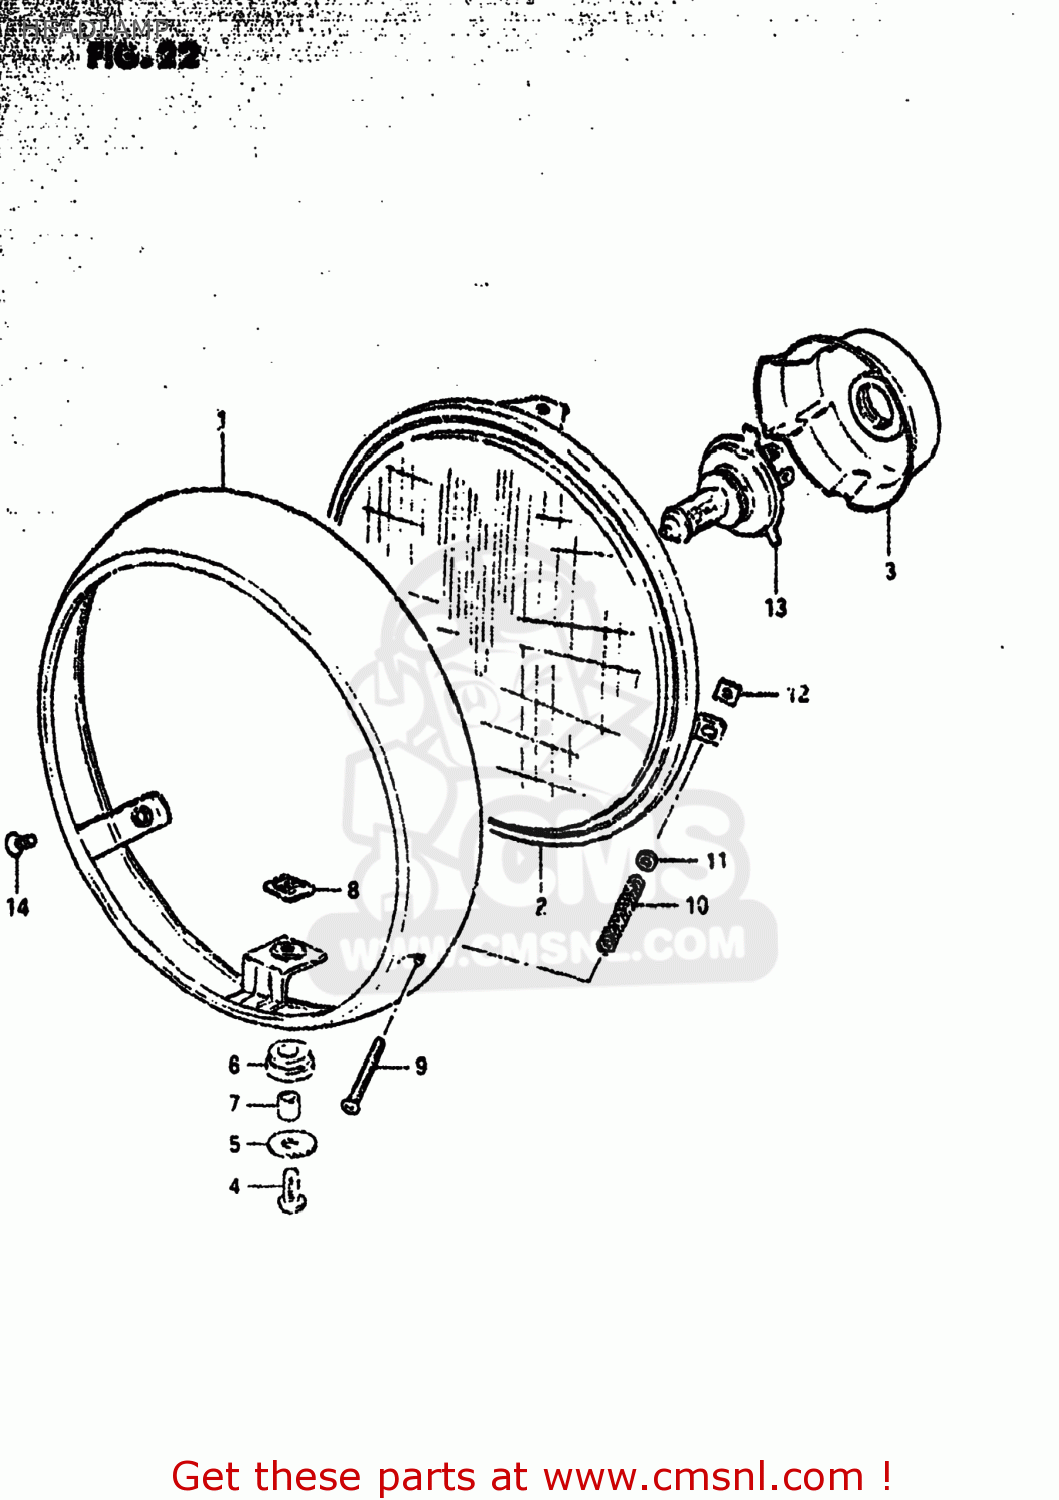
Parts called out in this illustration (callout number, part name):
1	RIM
2	LAMP UNIT
3	COVER,SOCKET
4	SCREW
5	WASHER
6	CUSHION
7	SPACER
8	NUT
9	SCREW
10	SPRING,HEADLAMP ADJUST
11	WASHER
12	NUT,HEADLAMP ADJUSTER
13	BULB(12V60/55W,H4)
14	SCREW
